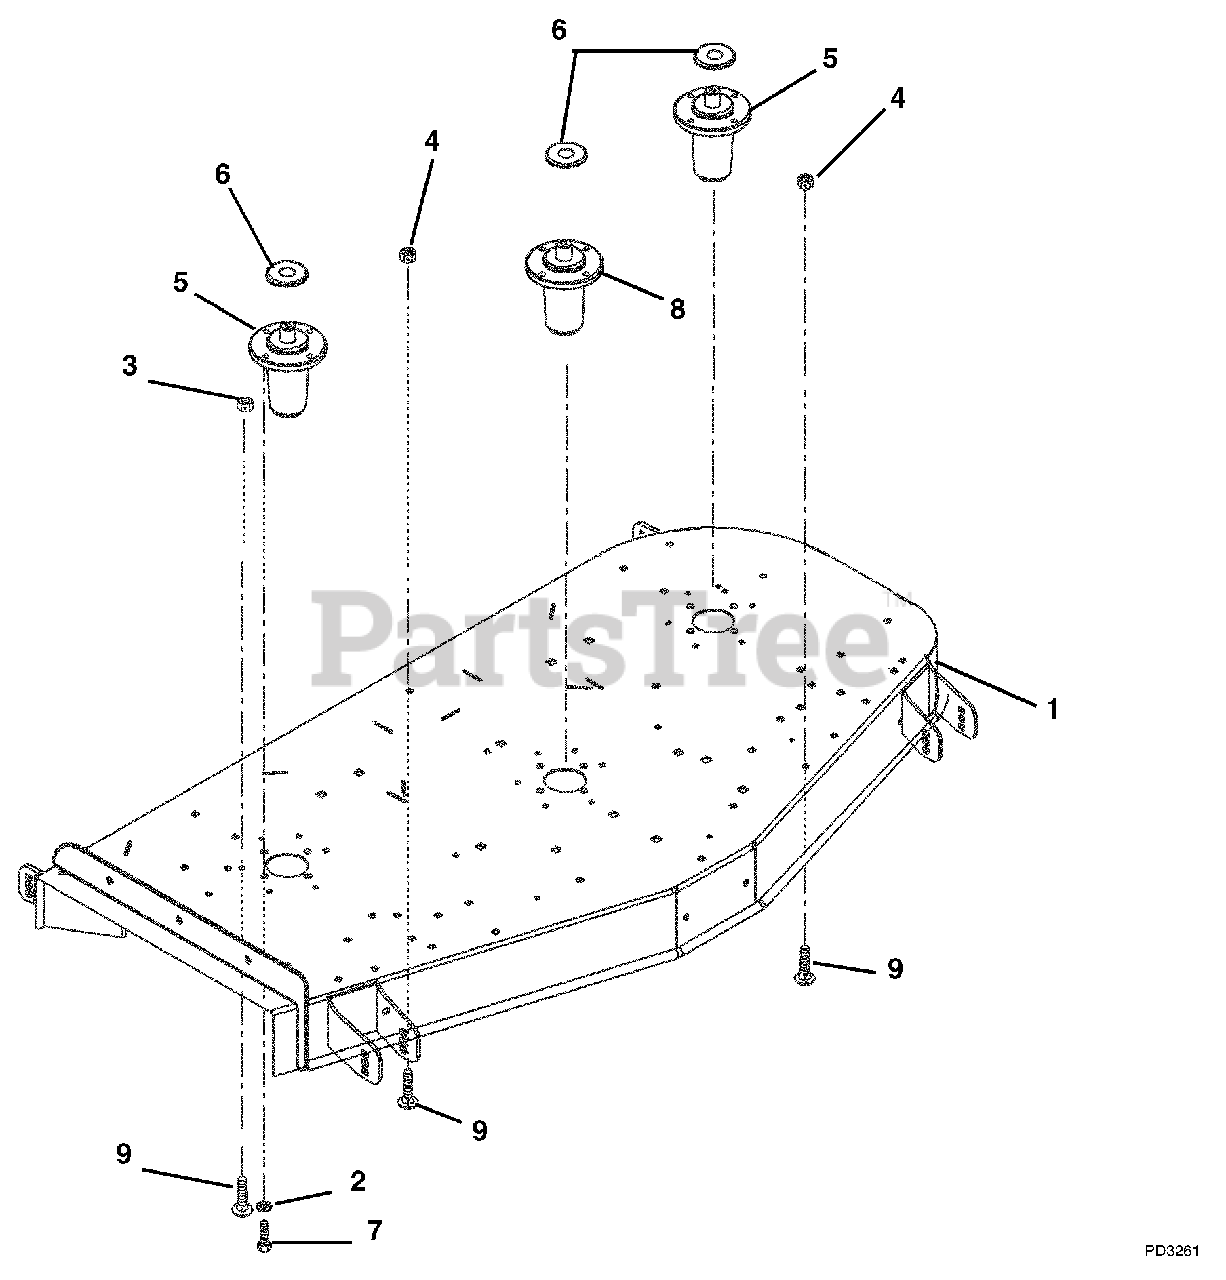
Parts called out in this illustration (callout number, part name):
1	Weldment, 72" Deck (Side Discharge)
2	Washer-Locking .38 x .094
3	Nut-Locking-Center .38-16
4	Nut-Locking-Nylon .38-16
5	Assembly, Spindle L-Hub
6	Slinger-Dust
7	Bolt-Hex .38-16 x 1.25 Grade 5
8	Spindle Assembly (Center)
9	Bolt-Round Head Square Neck .38-16 x 1.00 Grade 5
